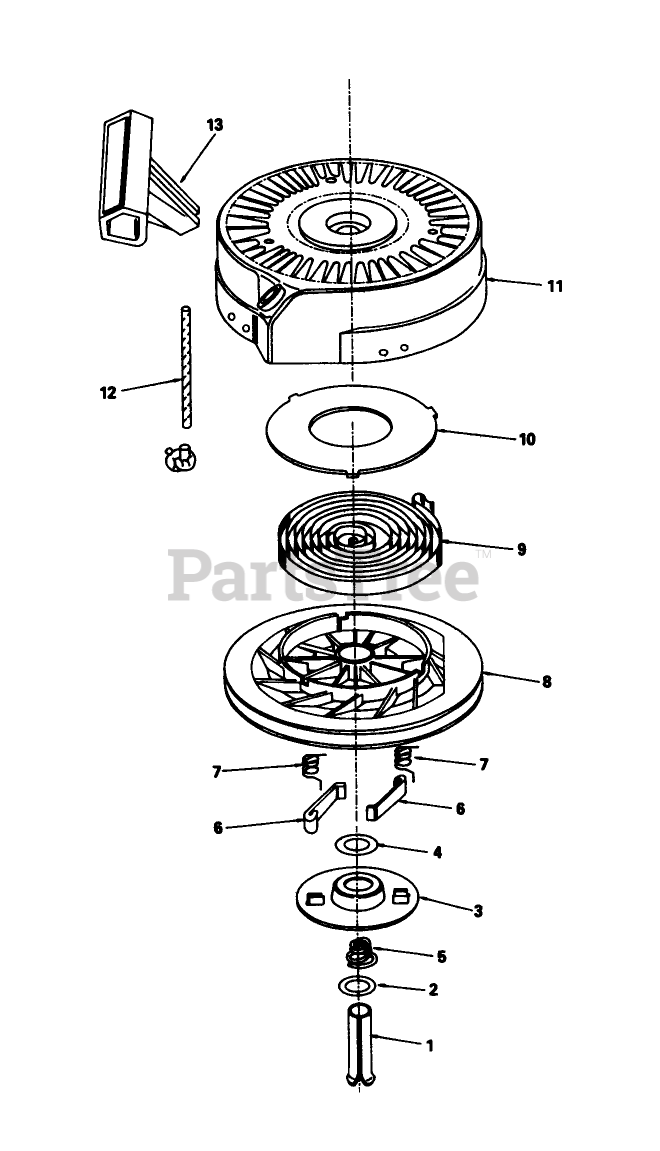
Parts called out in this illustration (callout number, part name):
1	Pin, Spring (Incl. Ref. #7)
2	Washer
3	Retainer
4	Washer
5	Brake Spring
6	Dog-Starter
7	Spring-Dog
8	Pulley
9	Rewind Spring
10	Cover-Spring
11	Housing-Starter
12	Rope-Starter (98 cut to length)
13	Handle-Starter
